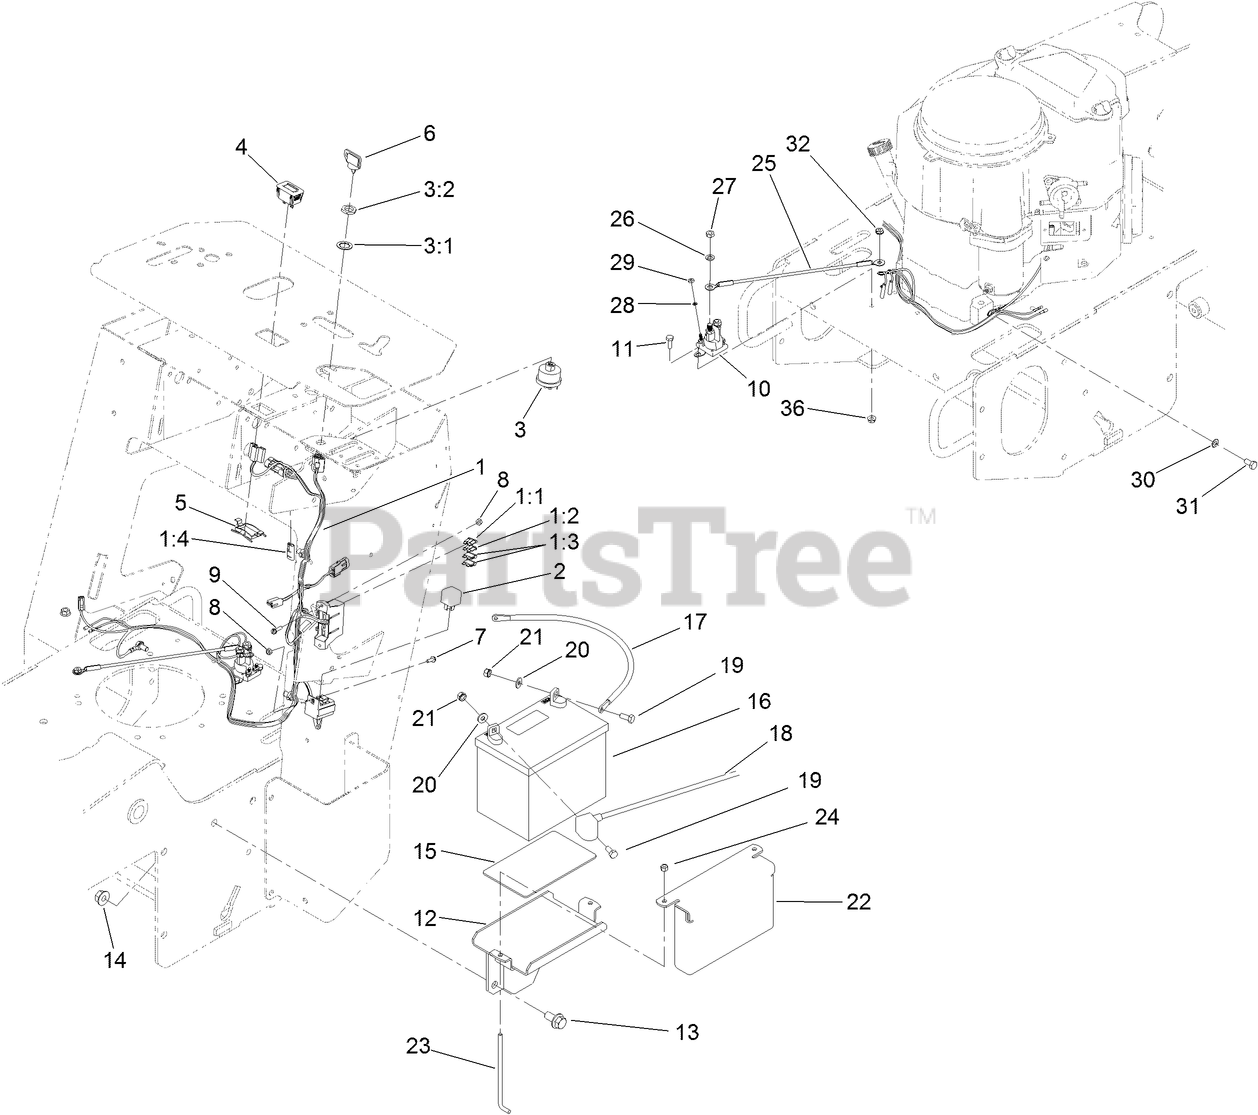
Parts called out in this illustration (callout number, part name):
1	HARNESS-WIRE
1:1	FUSE-BLADE, 30 AMP
1:2	FUSE-BLADE, 25 AMP
1:3	FUSE-BLADE, 15 AMP
1:4	CAP-PLUG
2	RELAY
3:1	WASHER-LOCK
3:2	NUT-HH
4	HOURMETER
5	CLIP-MOUNTING
6	KEY-IGNITION
8	NUT-LOCK, NI
9	SCREW-HWH
10	SOLENOID
11	SCREW-HH
12	TRAY-BATTERY
13	SCREW-HH
14	NUT-HHF
15	PAD-SKID, ANTI
16	BATTERY-DRY
17	CABLE-BATTERY, RED
18	CABLE-BATTERY, BLACK
19	SCREW-HH
20	WASHER-FLAT
21	NUT-KEPS
22	PLATE-HOLD DOWN, BATTERY
23	HOLDOWN-BATTERY
24	NUT-LOCK, NI
25	WIRE-SOLENOID/STARTER
26	SCREW-HH
27	NUT-JAM
28	WASHER-LOCK
29	NUT-HEX
30	WASHER-LOCK
31	SCREW-HH
32	NUT-KEPS
36	NUT-HF
